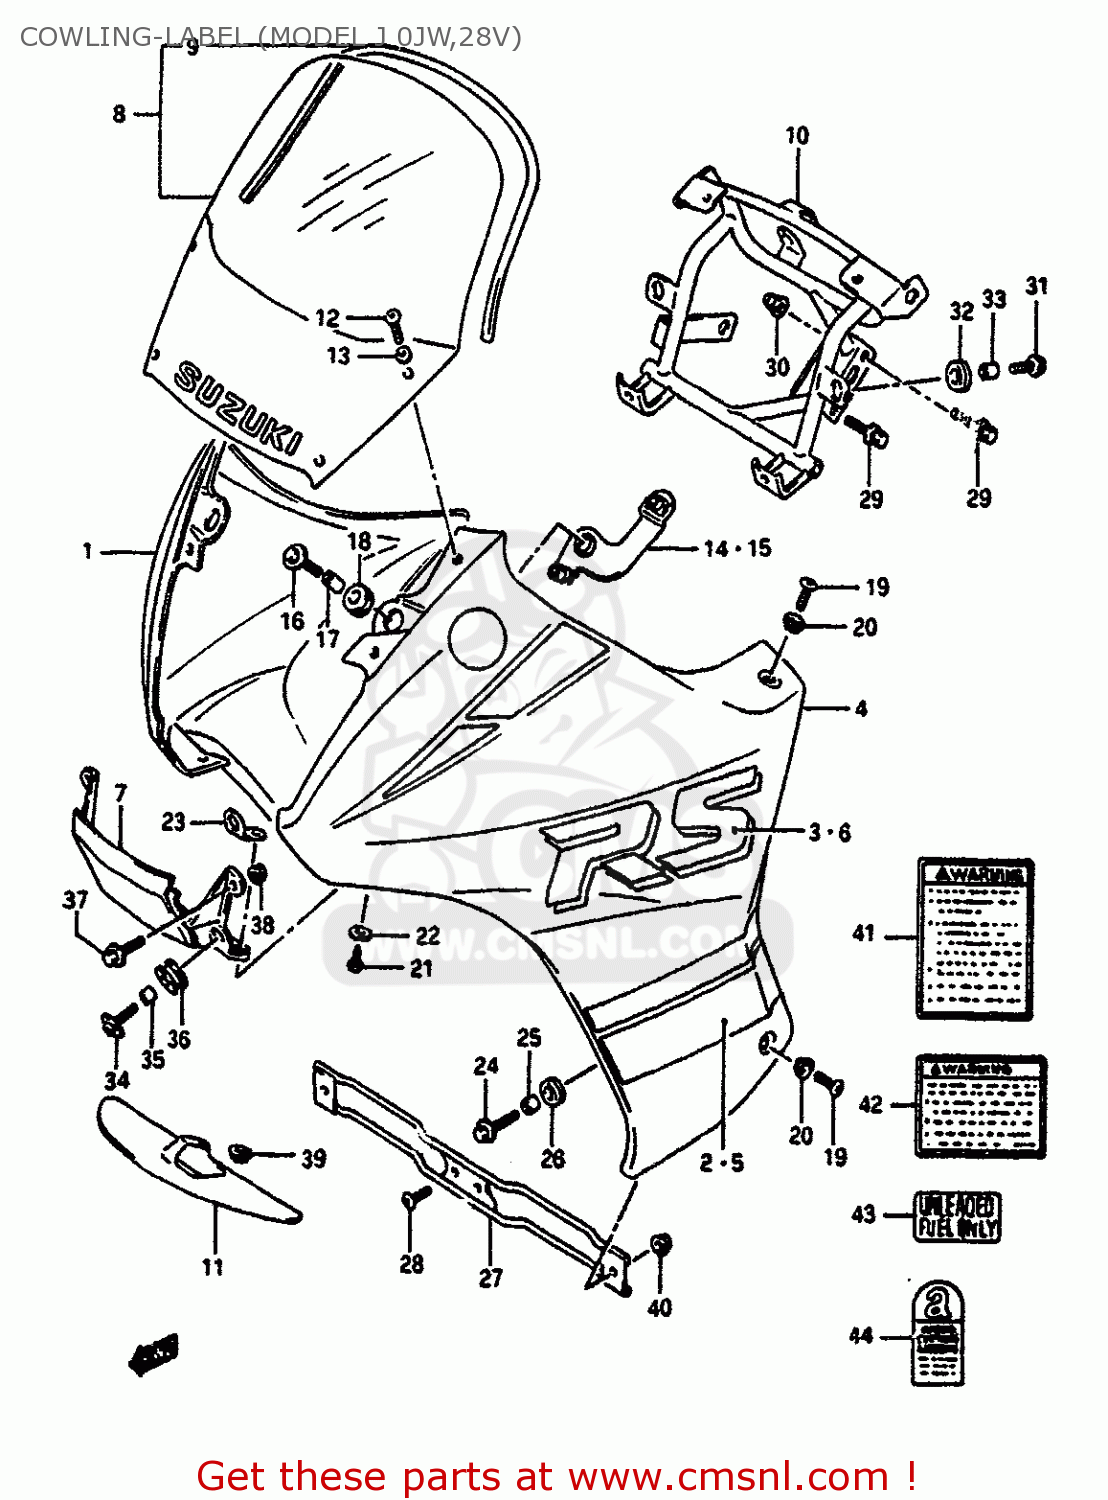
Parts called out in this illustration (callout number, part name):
1	COVER ASSY,COWL SIDE RH (RED)
2	TAPE SET,RH
3	EMBLEM
4	COVER ASSY,COWL SIDE LH (RED)
5	TAPE SET,LH
6	EMBLEM
7	COVER,COWL CENTER (RED)
8	WINDSCREEN
9	MOLDING
10	BRACE,COWLING
11	COVER,COWLING FR LWR
12	SCREW
13	WASHER(5.2X11X1)
14	BRACE,SCREEN,R
15	BRACE,SCREEN,L
16	SCREW
17	SPACER
18	CUSHION
19	SCREW(6X16)
20	WASHER(6.3X16X1.5)
21	SCREW (6X18)
22	WASHER(6.5X18X1.5)
23	BRACKET,COWLING FR LWR
24	SCREW(6X25)
25	SPACER (6.1X9X10)
26	CUSHION
27	BRACKET,COWL LOWER
28	SCREW
29	BOLT,BRACE
30	NUT M8
31	BOLT 6X20
32	CUSHION
33	SPACER (6.1X9X10)
34	SCREW
35	SPACER
36	CUSHION
37	SCREW,HEADLAMP (5X20)
38	NUT 5MM
39	WASHER (6.5X18X1.6)
40	NUT
41	LABEL (WARNING SCREEN)
42	LABEL, WARNING
43	LABEL,FUEL CAUTION
44	LABEL,ASBESTOS WARNING
